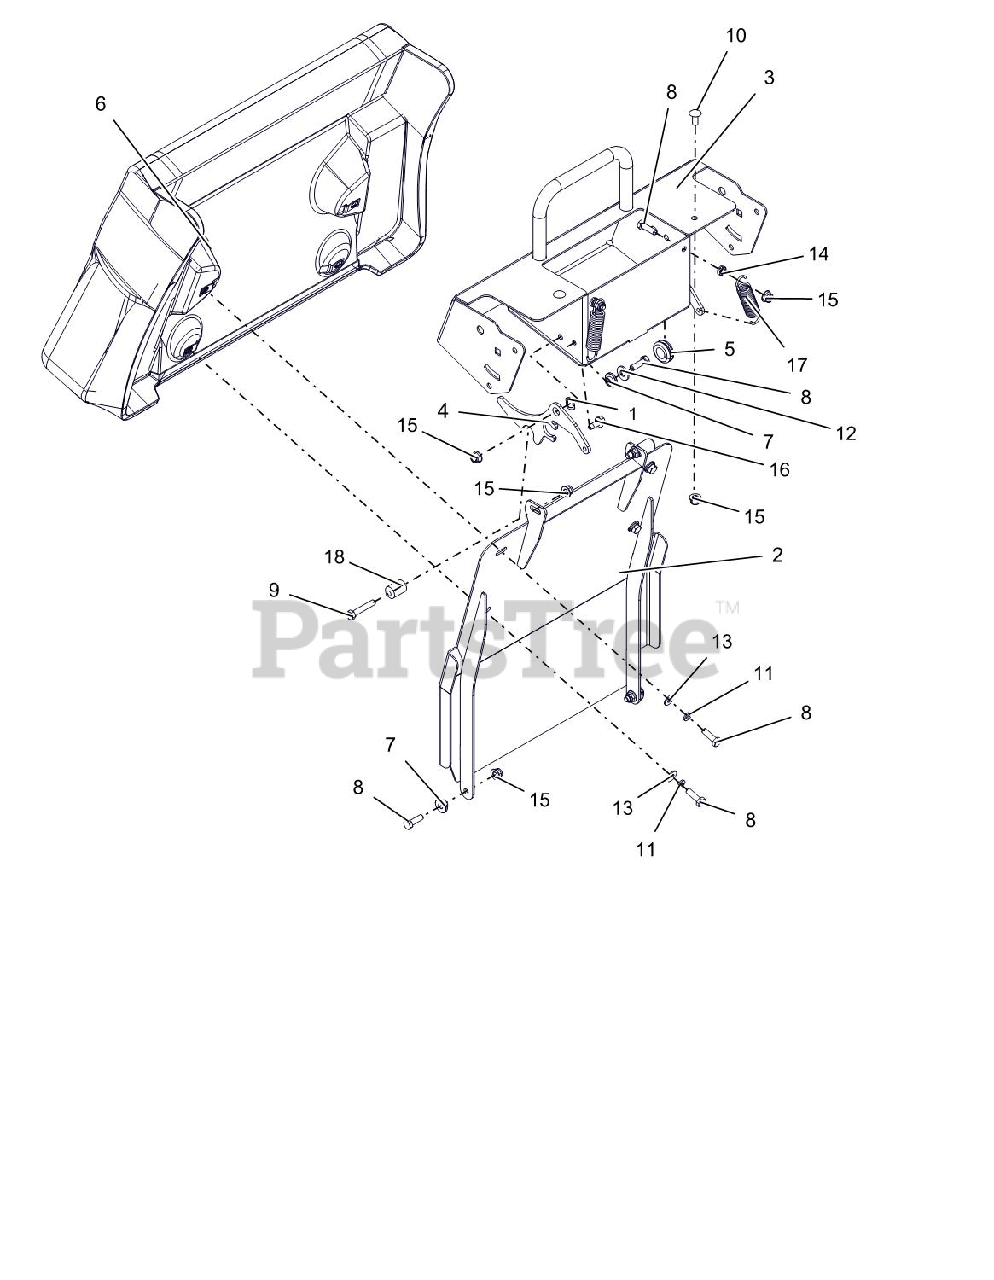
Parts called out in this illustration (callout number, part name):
1	WAVE WASHER .531X.781X.125FH
2	WLDMT, PAD MOUNT
3	WLDMT, CONTROL PANEL PROSTANCE
4	LATCH, PAD MOUNT
5	GROMMET, SPLIT RUBBER
6	PAD, PRO-STANCE OPERATOR
7	BSHG-FLG .32X.500X.344X.880
8	@BLT-HEX .31-18X1.00 GR5 YWZC
9	@BLT-HEX .31-18X1.75 GR5 YWZC
10	@BLT-RHDSSQNK .31-18X.75 G5YZ
11	@WSHR-LK .31X.078 REG YWZC
12	@WSHR-FL-STL.38X.875X.083 YWZC
13	@WSHR-FL-STL.312X.734X.065 YWZ
14	@NUT-LK-CTR-JAM .31-18 YWZC
15	@NUT-LK-NYL-FLG .31-18 YWZC
16	@SCR-TAP .31-18X.75 HWH TR YWZ
17	SG-TENS .105X.812X3.88 WLD 15
18	ECCENTRIC
